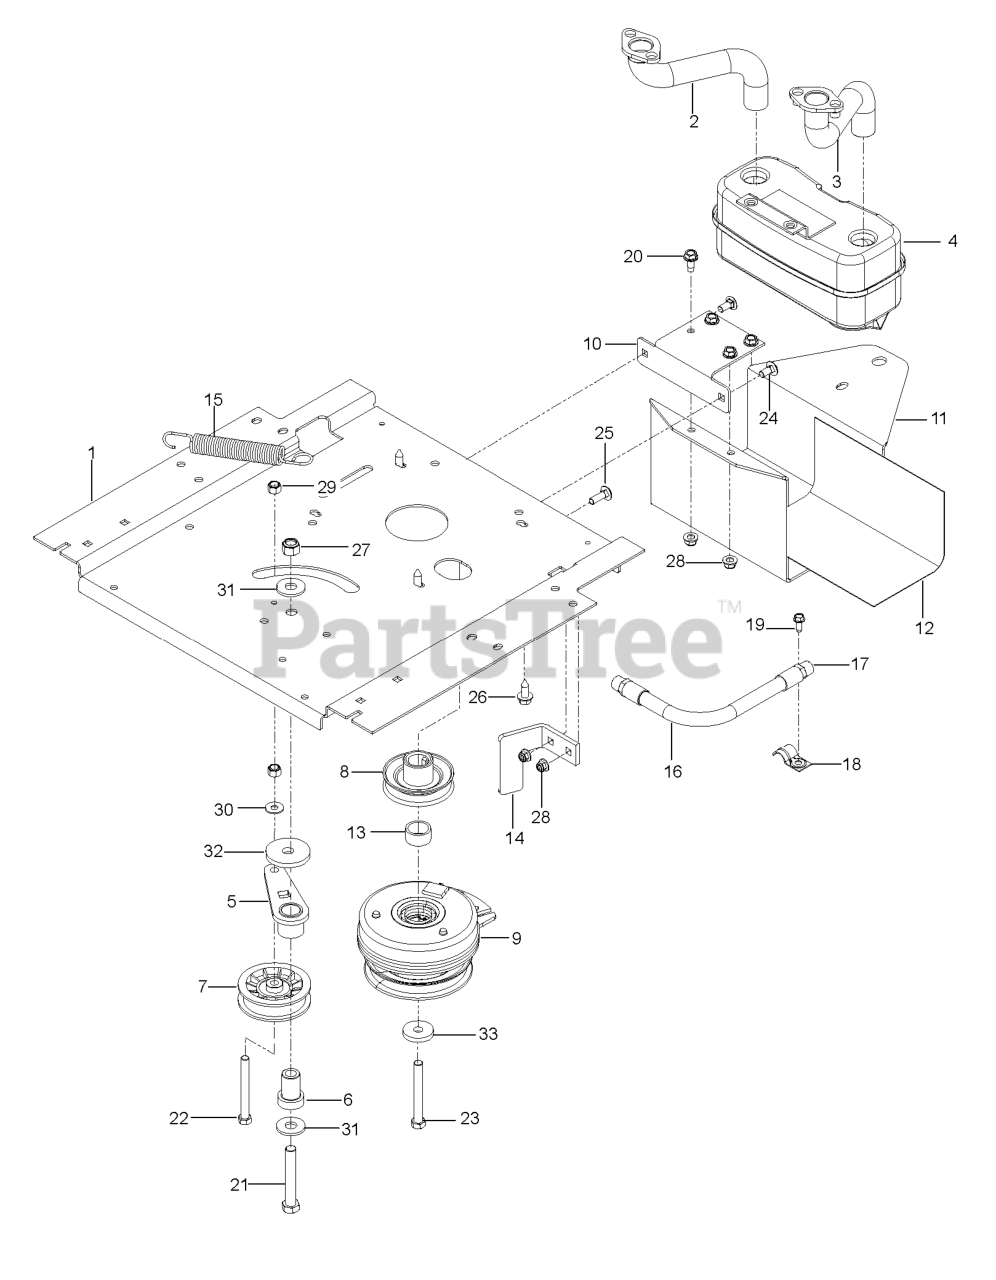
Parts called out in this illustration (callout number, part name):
1	PLATE ENGINE, BLACK
2	RP.EXHAUST.TUBE.LH.BS/TWIN
3	EXHAUST.TUBE.RH.BS/TWIN
4	MUFFLER ASM TWIN
5	RP.IDLER ARM WELDMENT
6	IDLER SPINDLE
7	PULLEY, IDLER RAKE & ZTR
8	PULLEY, ENGINE
9	CLUTCH, 105 FT-LBS
10	BRACKET, MUFFLER, BLACK
11	GUARD, MUFFLER, BLACK
12	HEAT SHIELD
13	T & B SPACER
14	STOP, CLUTCH, BLACK
15	SPRING, DECK DRIVE
16	OIL DRAIN HOSE
19	SCREW 1/4 X 5/8
20	SCREW.THDROL.5/16-18X3/4.TTY
21	HCS 1/2-13 X 3-1/4 GD 5 ZD
22	HCS 3/8-16X3-1/2 TAPBLT GR5 ZD
23	HCS 7/16-20X3-1/2 GR 5 ZN
24	BOLT 5/16C X 3/4" CARRIAGE
25	RHSNB 5/16C X 1
26	HHFS 3/8-16 x 1 THD FRM
27	NUT 1/2-13 HEX NYLOC ZD
28	5/16-18 NYLOC FLANGE NUT
29	NUT 3/8-16 NYLOC
30	WASHER 5/16 FLAT
31	WASH USS FLAT 1/2
32	HEAVY WASHER
33	CLUTCH, WASHER
